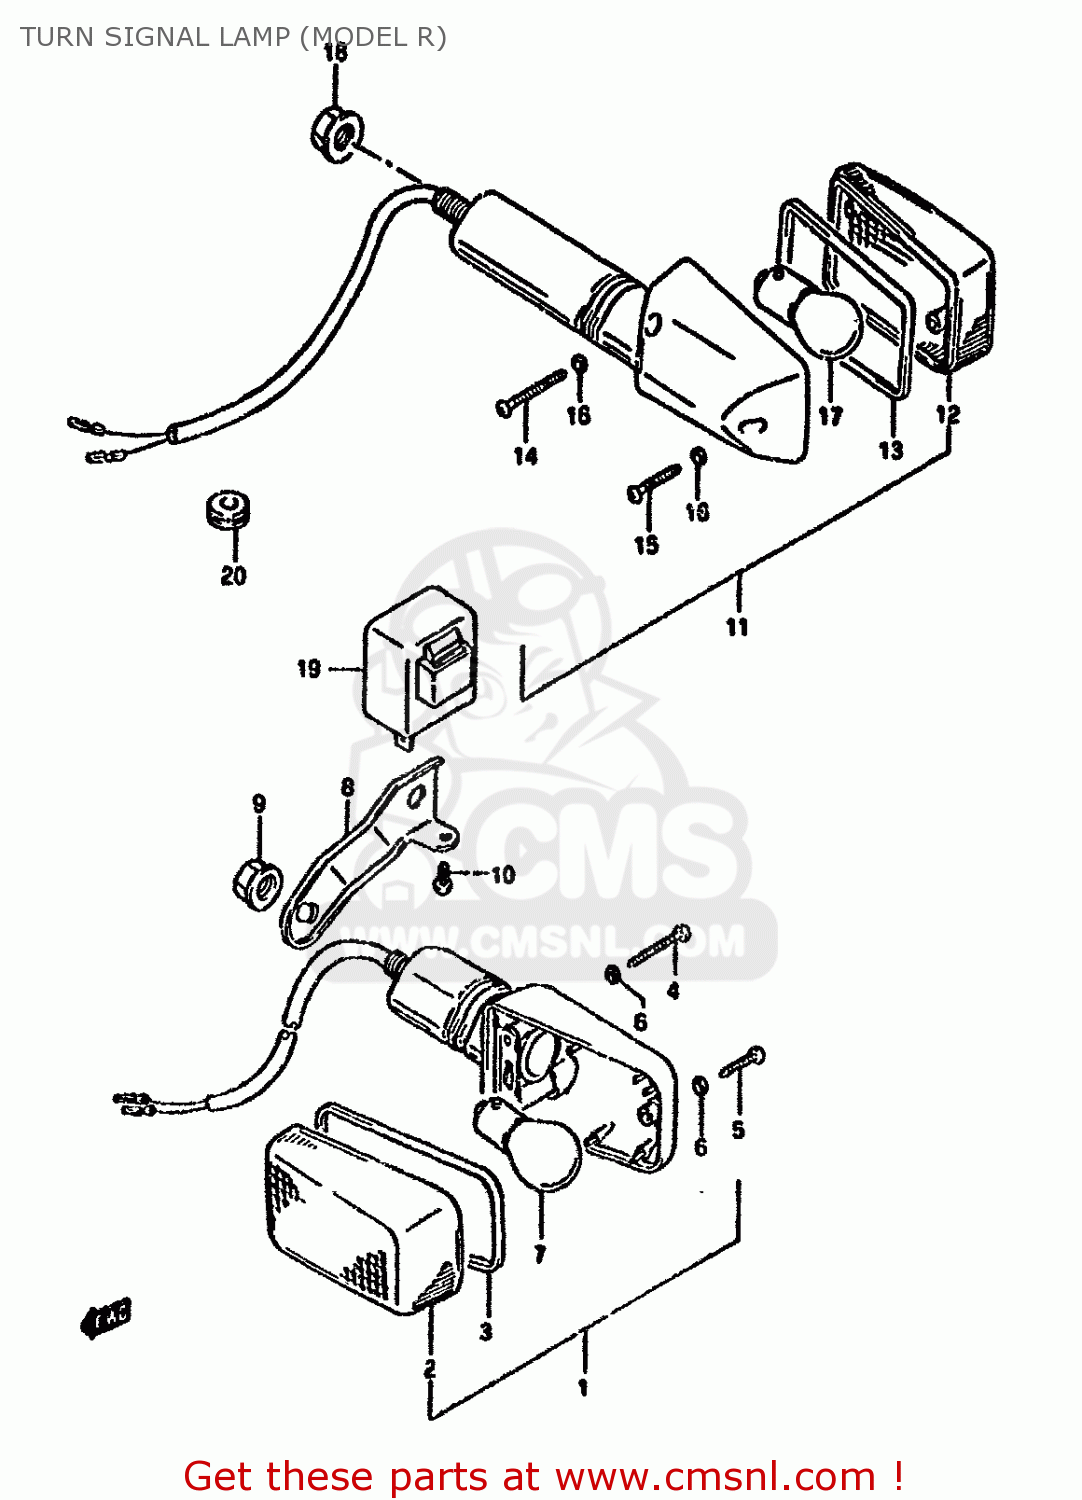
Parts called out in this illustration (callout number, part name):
1	LAMP ASSY,FR TURN SIGNAL
2	LENS
3	GASKET (NAS)
4	SCREW(3X30)
5	SCREW
6	GASKET (NAS)
7	BULB(12V21W)
8	BRACKET,FRONT TURN SIGNAL
9	NUT
10	SCREW
11	LAMP ASSEMBLY,REAR TURN SIGNAL
12	LENS
13	GASKET (NAS)
14	SCREW(3X30)
15	SCREW
16	GASKET (NAS)
17	BULB(12V21W)
18	NUT
19	SCREW
20	GROMMET
21	GROMMET
